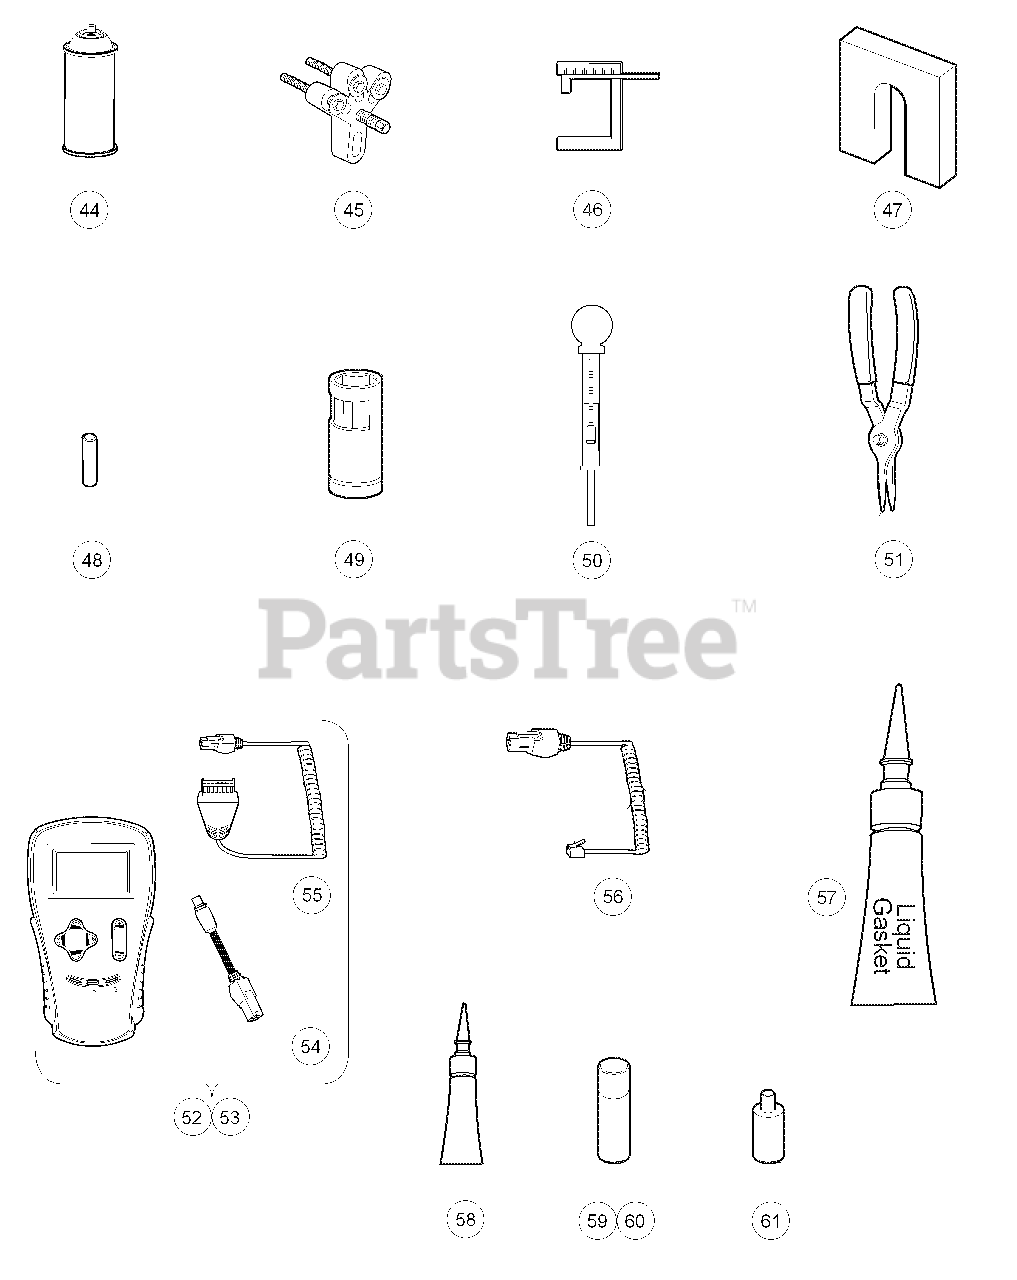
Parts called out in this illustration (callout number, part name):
44	Dry Moly Lubricant
45	Flywheel Puller Kit
46	Gauge, Carburetor Float Level
48	Governor Shaft Installation Tool
49	Hydraulic Brake Adjuster
50	Hydrometer
51	Internal Retaining Ring Pliers
52	IQ Display Module (IQDM) Kit
53	IQ Display Module (IQDM-P) Kit
54	Adaptor, Cable
55	IQDM Series 2 Cable
56	IQDM Series 1 Cable
57	Liquid Gasket
58	Moly-Teflon Lubricant
59	Paint, Touch-Up – Beige
59	Paint, Touch-Up – Black
59	Paint, Touch-Up – Burgundy
59	Paint, Touch-Up – Classic Blue
59	Paint, Touch-Up – Dark Gray
59	Paint, Touch-Up – Dark Green
59	Paint, Touch-Up – Gray
59	Paint, Touch-Up – Red
59	Paint, Touch-Up – Royal Blue
59	Paint, Touch-Up – White
60	Paint, Precedent Underbody – Gray
61	Paint Pen, Touch-Up, Precedent Underbody – Black
